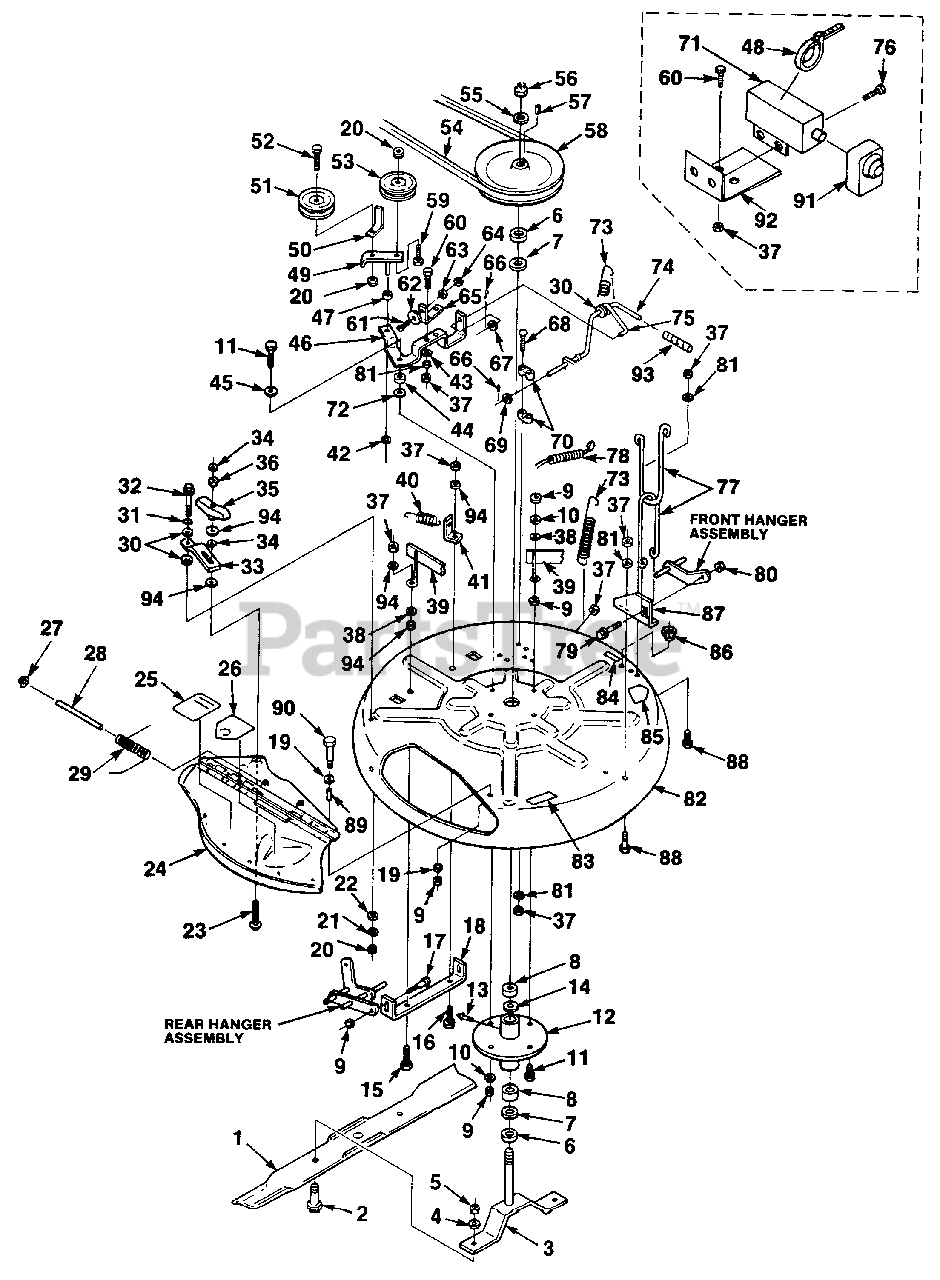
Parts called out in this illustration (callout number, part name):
1	BLADE- Hi-Lift
2	SCREW- Hex centerlock 1/2-13 x 1 1/4"
3	SPINDLE & ADAPTOR
4	WASHER- Lock 1/2"
5	NUT- Hex centerlock 1/2-13
7	WASHER- Flat
9	NUT- Hex centerlock 5/16-18
10	WASHER- Lock 5/16"
11	SCREW- Hex centerlock 5/16-18 x 1 1/2"
12	SPINDLE HOUSING
13	FITTING- Lubrication
14	SPACER- Bearing
15	SCREW- Hex centerlock 1/4-20 x 1 1/4"
16	SCREW- Hex centerlock 1/4-20 x .875
17	BOLT- Shoulder 5/16-18
18	BRACKET- Rear lift
19	WASHER- Plain 5/16"
20	NUT- Hex centerlock 3/8-16
21	WASHER- Lock 3/8"
22	WASHER- Plain 3/8"
23	BOLT- Carriage 1/4-20 x 1 1/4"
24	PLATE & COVER
25	DECAL- Door
26	DECAL-CPSC
28	ROD- Deck hinge
29	SPRING- Torsion
30	WASHER- Plain
31	WASHER- Spring
32	BOLT- Shoulder
33	ARM- Pivot
34	WASHER- Speed
35	KNOB- Handle
36	NUT- Hex 1/4-20
37	NUT- Hex centerlock 1/4-20
38	WASHER- Flat 5/16"
39	GUIDE- Belt
40	SPRING- Extension
41	BRACKET- Damper
42	RING- Retainer
43	WASHER- Plain
45	WASHER- Engine
46	BRAKE/CLUTCH- Lever
48	STA-STRAP
49	IDLER- Pivot
50	GUIDE- Belt
51	PULLEY- Idler
52	SCREW- Hex centerlock 3/8-16 x 1 3/4"
53	PULLEY- Idler
54	BELT- Mower Deck
56	NUT- Hex lock
58	PULLEY- Spindle
59	BOLT- Carriage 3/8-16 x 1 3/4"
60	SCREW- Hex centerlock 1/4-20 x 3/4"
61	SCREW- Truss hd. 10-24 x 1/2"
62	PAD- Brake
63	WASHER- Plain #10
64	NUT- Hex centerlock #10-24
65	BRACKET- Brake pad
66	PIN- Cotter
67	WASHER- Plain 3/8"
68	BOLT- Carriage 1/4-20 x 1 1/2"
69	WASHER- Plain
71	SWITCH- Deck
72	WASHER- Plain
73	SPRING- Extension
74	LEVER- P.T.O.
75	ROD- Link
76	SCREW- Taptite
77	LINK- Lift
78	COVER- Cable
79	BOLT- Shoulder 3/8-16
80	NUT- 3/8-16
81	WASHER- Lock 1/4"
82	DECK- 30"
83	DECAL- Warning
84	DECAL- No step
85	DECAL-CPSC
86	PLUG- Washout
87	BRACKET- Front lift
88	SCREW- Hex centerlock 1/4-20 x 5/8"
90	SCREW- Hex center lock 5/16-18 x 5/8"
91	SWITCH- Boot
92	BRACKET- Deck switch
93	COVER- Lift handle
94	WASHER- Plain 1/4"
